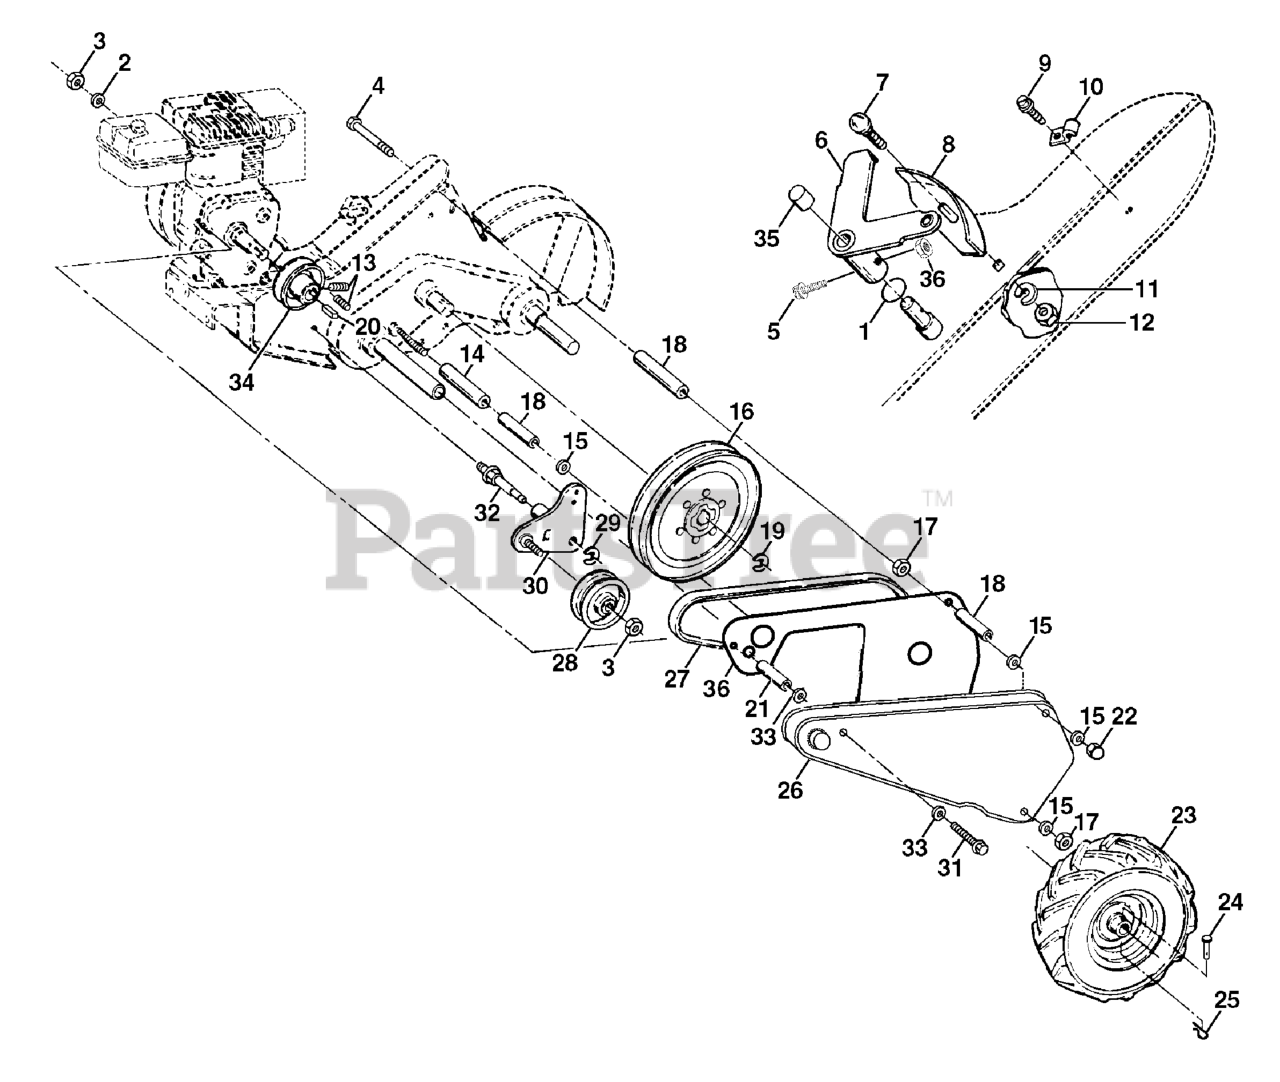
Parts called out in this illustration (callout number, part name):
2	WASHER, LOCK 3/8
3	NUT.HEX.3/8-16UNC
4	BOLT 5/16-18X4 1/2
5	SCREW, SHIFT LEVER
6	LEVER ASM CRT
8	PANEL.INDICATOR.SHIFT.BLACK
9	TAPPING SCREW
10	CONDUIT.CLIP.PLATED
11	LOCKWASHER
12	NUT
14	SPACER, SPLIT
15	WASHER
16	SHEAVE, TRANSMISSION
17	NUT
19	RETAINING RING LT
20	KEY, SQUARE
21	SPACER.SPLIT
23	TIRE.16X4-8.CHEVRON.TILLER
23	RIM
23	VALVE STEM LT
25	SPRING TI
26	BELT GUARD
27	BELT, DRIVE
28	PULLEY-IDLER TI
30	BRACKET.ASM.IDLER.BLACK
31	Bolt, Hex Head 1/2-20 x 2-3/4
32	SHAFT, IDLER ARM
33	WASHER
34	SHEAVE, ENGINE
35	CAP.PLUNGER.BLACK
